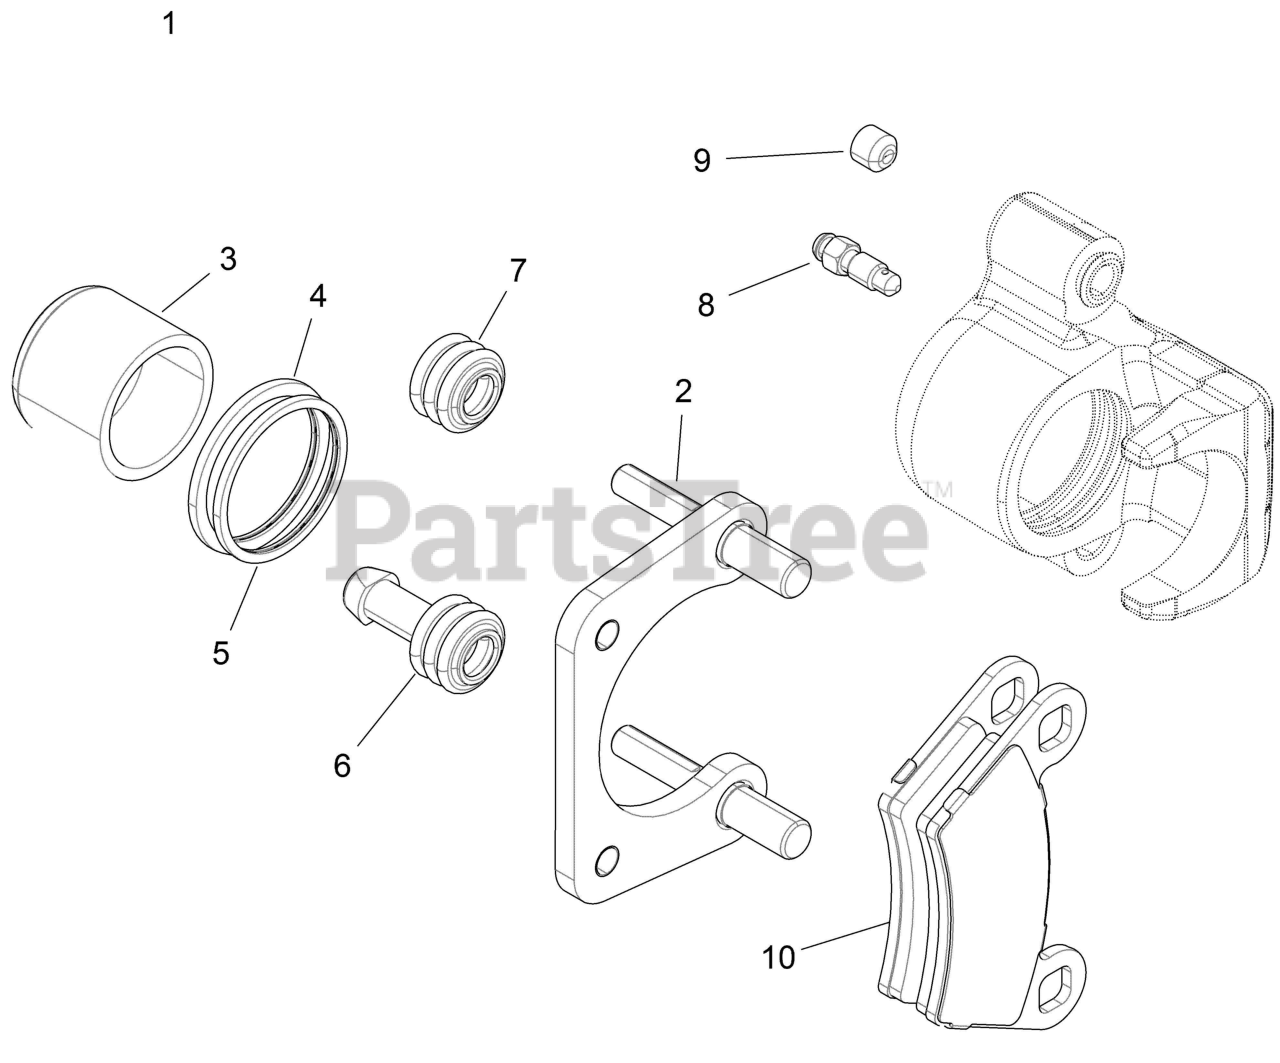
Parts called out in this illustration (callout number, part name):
1	ASM-CALIPER,BRAKE,1.5,LH,R MET
1	ASM-CALIPER,BRAKE,1.5,RH,R MET
2	ASM-CALIPER MOUNT,REAR,METRIC
3	PISTON-BRAKE,1.500
4	SEAL-CALIPER INNER,1.50"
5	SEAL-CALIPER,OUTER,1.50"
6	BOOT-PIN BUSHING
7	BOOT-PIN SEAL
8	SCR-M7X1.0,BLEEDER,OLIVE D
9	SCR-M10X1.0X8,SOC SET-OD
10	KIT-BRAKE PAD,ASM,1.5(INCL 4 P
